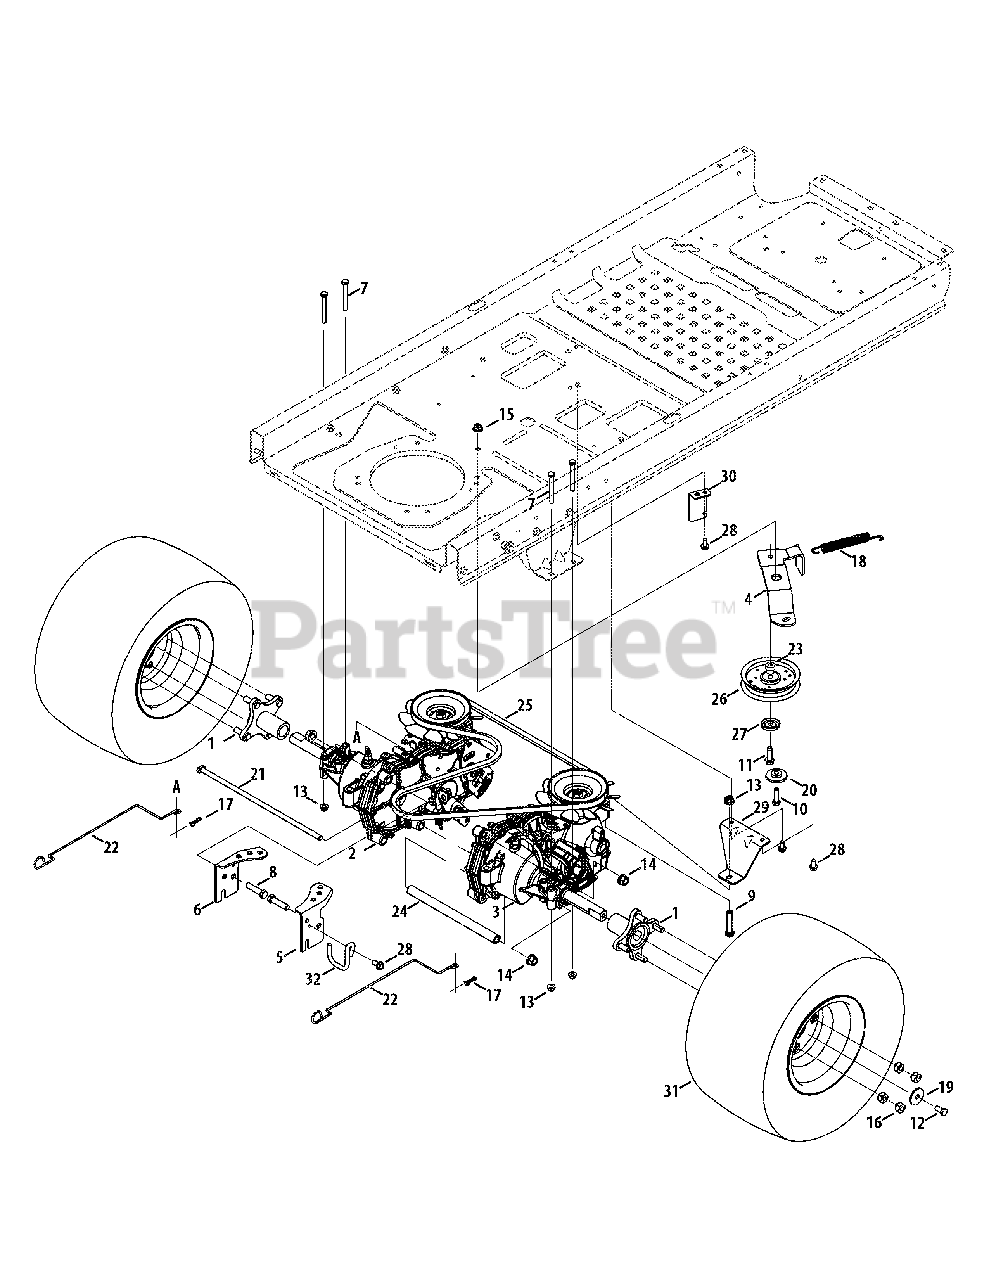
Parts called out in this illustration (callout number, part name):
1	Wheel Hub Assembly
2	LH Transmission
3	RH Transmission
4	Hydro idler Bracket
5	RH transmission Mount Bracket
6	LH transmission Mount Bracket
7	Hex Screw, 5/16-18 x 2.75
8	Hex Screw, 7/16-20 x 1.750
9	Screw-HHCS 5/16-18 x 2.25
10	Hex Screw, 3/8-16 x 1.00
11	Hex Washer Screw, 3/8-16 x 1.250
12	Hex Screw, 3/8-16 x .750
13	Flange Lock Nut, 5/16-18
14	Flange Lock Nut, 7/16-20
15	Jam Lock Nut, 3/8-16
16	Lug Nut, 7/16-14
17	Cotter Pin
18	Extension Spring.75 x 5.365
19	Flat Washer, .390 x 1.500 x .134
20	Shoulder Spacer, .8840 x .190
21	Rod, .405 x 14.0
22	Bypass Rod
23	Toggle Lock Shoulder Spacer
24	Tube, .51 x .75 x 10.2
26	Idler Pulley, 4.25
27	Pulley Cap
28	Hex Washer Screw, 5/16-18 x .750
29	Transmission Mount Bracket
30	Spring Mount Bracket
31	Wheel Assembly, 18 x 9.5-8
32	Clutch Keeper Rod
